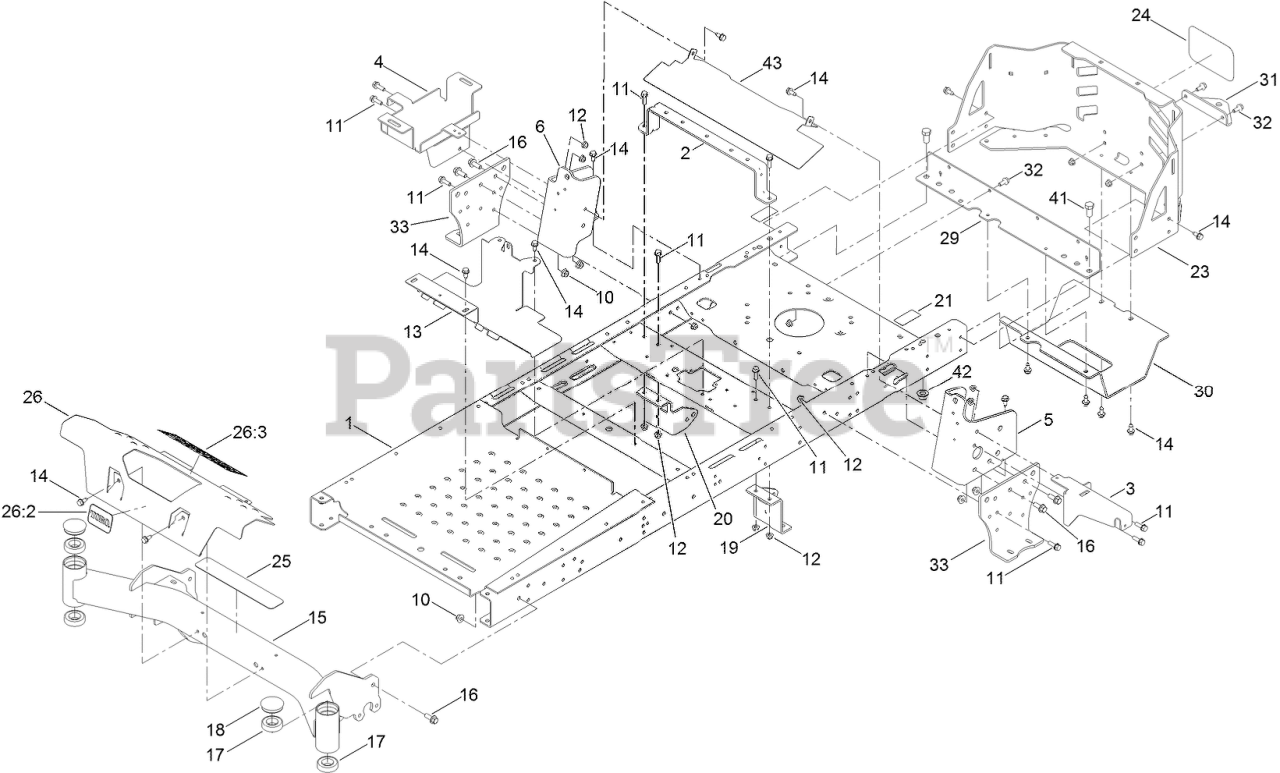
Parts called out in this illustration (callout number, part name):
1	FRAME ASM
2	BRACE-SEAT, REAR (WIDE)
3	BRACKET-SUPPORT, POD (LH)
4	TRAY-BATTERY
5	BRACKET-MOUNTING, LH
6	BRACKET-MOUNTING, RH
10	NUT-HF, NI
11	SCREW-HHF
12	NUT-HF, NI
13	BRACKET-MOUNT
14	SCREW-HWHTF
15	AXLE-FRONT
16	SCREW-HHF
17	BEARING-BALL
18	CAP-GREASE
19	MOUNT-HYDRO, FRONT (LH)
20	MOUNT-HYDRO, FRONT (RH)
21	DECAL-BYPASS
23	GUARD-ENGINE
24	DECAL
25	TREAD-STEP
26	FOOTREST
26:3	DECAL-DANGER
30	GUARD-MUFFLER
31	BRACKET-HITCH
32	SCREW-HHF
33	MOUNT-HYDRO
41	SCREW-HH
42	NUT-LOCK
